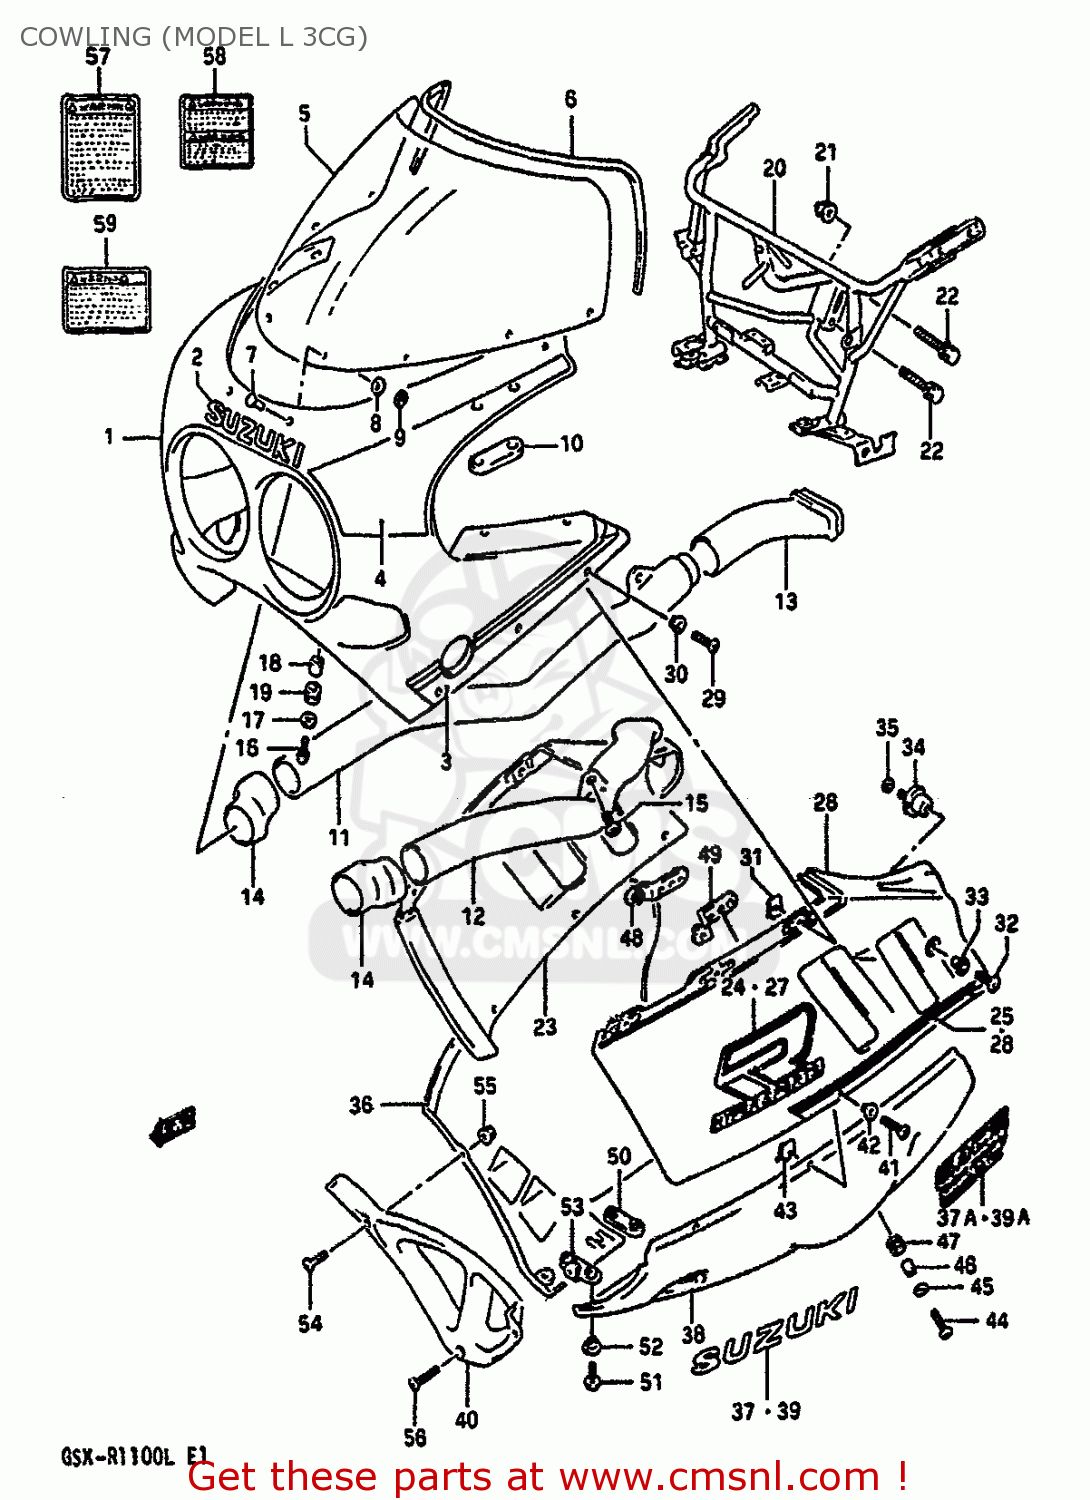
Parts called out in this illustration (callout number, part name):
1	BODY ASSY,COWLING
2	EMBLEM,COWLING FR
3	TAPE SET,COWLING,UPPER
4	TAPE SET,COWLING,UPPER,FRONT
5	SCREEN,WIND
6	MOLDING
7	PIN,WINDSCREEN
8	CUSHION
9	NUT
10	CUSHION,RR VIEW MIRRORR
11	PIPE,AIR INTAKE FR,R
12	PIPE,AIR INTAKE,FRONT
13	PIPE,AIR INTAKE RR,R
14	JOINT,AIR INTAKE
15	SCREW, CENTER
16	SCREW(6X20)
17	WASHER(6.5X18X1)
18	SPACER
19	CUSHION
20	BRACE,COWLING
21	NUT ,8MM
22	BOLT
23	COVER ASSEMBLY,COWLING
24	EMBLEM,COWLING SIDE,RIGHT
25	TAPE,COWLING SIDE,RIGHT
26	COVER COMP,COWLING SIDE,LEFT
27	EMBLEM,COWLING SIDE,L
28	TAPE,COWLING SIDE,LEFT
29	SCREW(5X18)
30	WASHER(5.2X14X1.5)
31	NUT,HEADLAMP HOUSING,UPPER
32	SCREW(6X12)
33	WASHER(6.3X16X1.5)
34	CUSHION,COWLING
35	WASHER,LOCK
36	COWLING,UNDER,
37	EMBLEM
37A	EMBLEM,SACS
38	COWLING,UNDER,
39	EMBLEM,COWLING UNDER,L
39A	EMBLEM,SACS
40	COWLING,UNDER,CENTER
41	SCREW(5X18)
42	WASHER(5.2X14X1.5)
43	NUT,HEADLAMP HOUSING,UPPER
44	SCREW(6X20)
45	WASHER(6.5X18X1)
46	SPACER
47	CUSHION
48	BRACKET
49	BRACE,COWLING UNDER,LH
50	BRACE,COWLING LWR COVER RR
51	SCREW(6X16)
52	WASHER(6.3X16X1.5)
53	BRACE,COWLING LWR COVER
54	SCREW(5X14)
55	NUT
56	SCREW(6X16)
57	LABEL (WARNING SCREEN)
58	LABEL (WARNING)
59	LABEL, WARNING SAFETY
